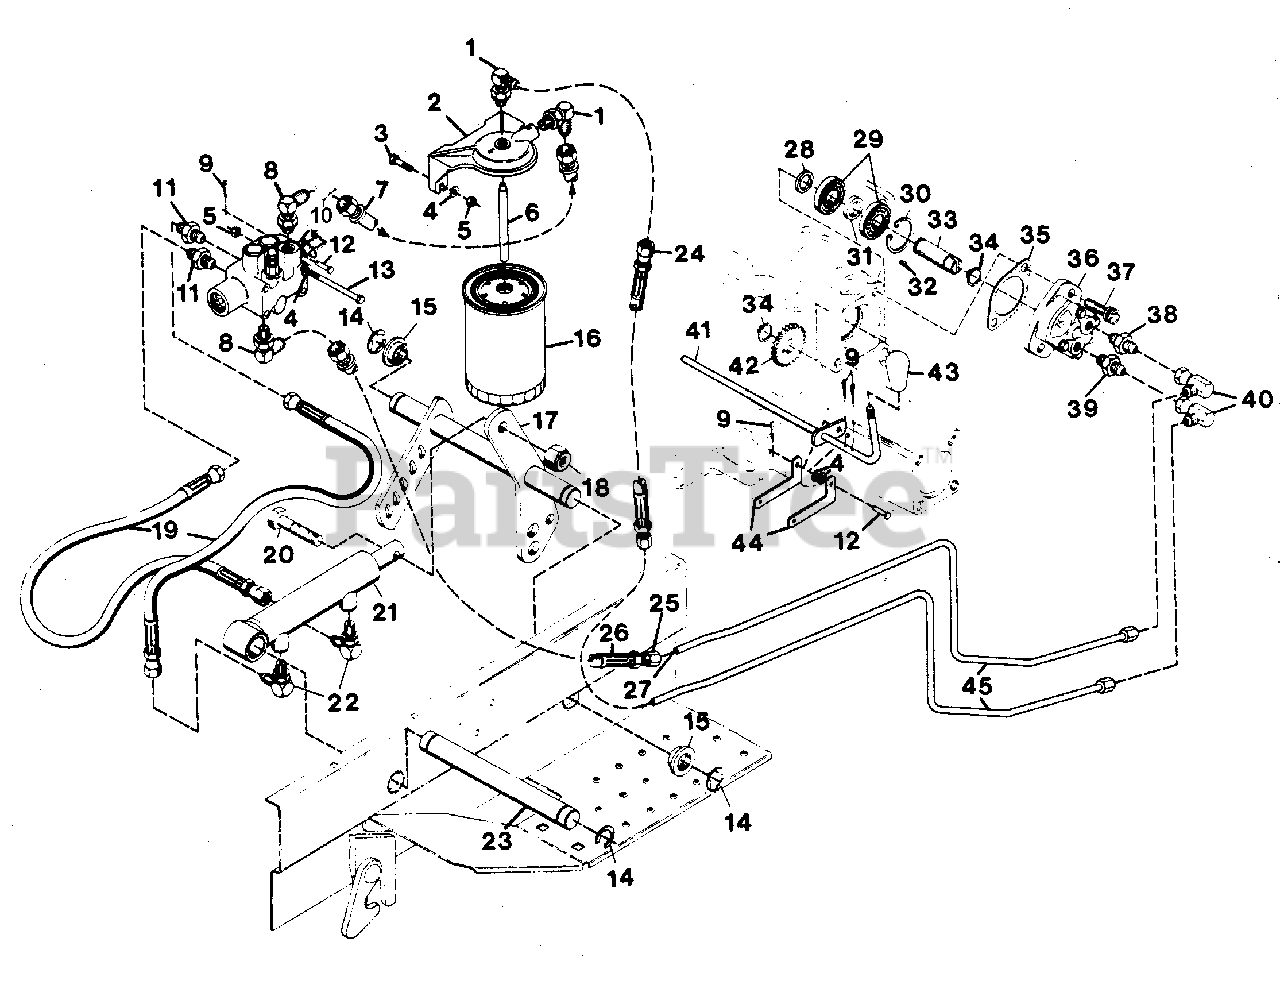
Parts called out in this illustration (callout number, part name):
1	ADAPTER
2	BRACKET, OIL FILTER
3	BOLT, HEX 1/4-20X1.00
4	WASHER, FLAT .281X.625X.065
5	NUT, LOCK 1/4-20
6	TUBE, OIL PICK-UP
7	HOSE, HYDRAULIC VALVE TO TANK
8	ADAPTOR(P-H #2503-6-6)
9	PIN, COTTER .094X.75
10	VALVE, HYDRAULIC
11	ADAPTOR(P-H #0503-4-4)
12	PIN, CLEVIS
13	BOLT, HEX 1/4-20X2.75
14	E-RING, 1.000 SHAFT
15	BUSHING, PIVOT
16	FILTER, SPIN-ON
17	WELDMENT, LIFT LEVER SHAFT
18	NUT, LOCK 1/2-13
19	HOSE, HYDRAULIC 14.5
20	BOLT, HEX 1/2-13X2.00
21	CYLINDER, HYDRAULIC
22	ADAPTOR(P-H #2503-4-4)
23	SHAFT, HYDRAULIC CYLINDER
24	HOSE, HYDRAULIC
25	NUT, FEMALE FLARELESS
26	HOSE, HYDRAULIC PUMP TO VALVE
27	SLEEVE, FEMALE FLARELESS
28	SPACER, .620X.750X.276
29	BEARING, BALL .590X1.378X.433
30	RING, RETAINING 1.378 BORE
31	SPACER, .620X.750X.364
32	KEY, WOODRUFF .125X.375 HARD
33	SHAFT, HYDRAULIC PUMP
34	RING, RETAINING .594 SHAFT
35	GASKET, COVER PLATE
36	PUMP, HYDRAULIC
37	SCREW, CAP 3/8-16 HEX SOCKET HD
38	ADAPTOR
39	ADAPTOR(P-H #0503-10-6)
40	ADAPTOR(P-H #3903-6-6)
41	WELDMENT, HYDRAULIC CONTROL ROD
42	GEAR, HYDRAULIC PUMP
43	KNOB, PTO
44	ROD, HYDRAULIC CONTROL
45	LINE, HYDRAULIC IN
